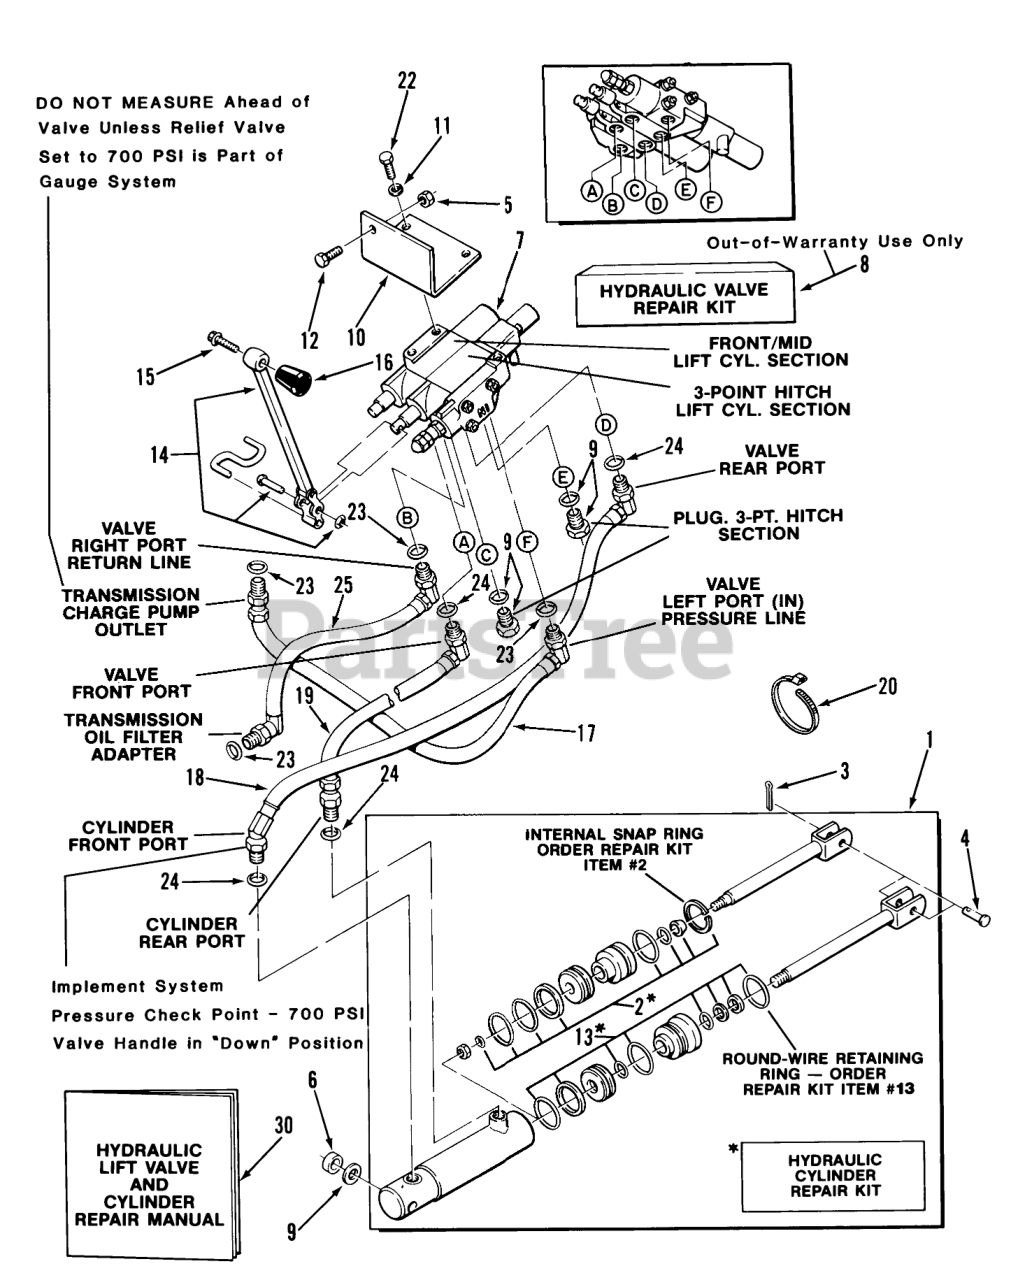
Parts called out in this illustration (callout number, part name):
1	CYLINDER
2	S/A O-RING&GASKET AS
4	CLEVIS PIN
5	Nut
6	Spacer
7	Hydraulic Valve
8	S.A. Repair Kit
9	Plug (With 973310 0-Ring)
10	Mounting Bracket
11	Lockwasher
12	Bolt
13	S/A 108872 HYD CYL
14	S/A HANDLE&HARDWARE
15	SCREW
17	ASSY-HYDRAULIC HOSE
18	Hydraulic Hose Assy
19	HYD HOSE ASSY
20	PLASTIC TIE
22	Bolt
23	0-Ring
24	O RING
25	Hose-Transmission To Valve
30	Repair Manual
